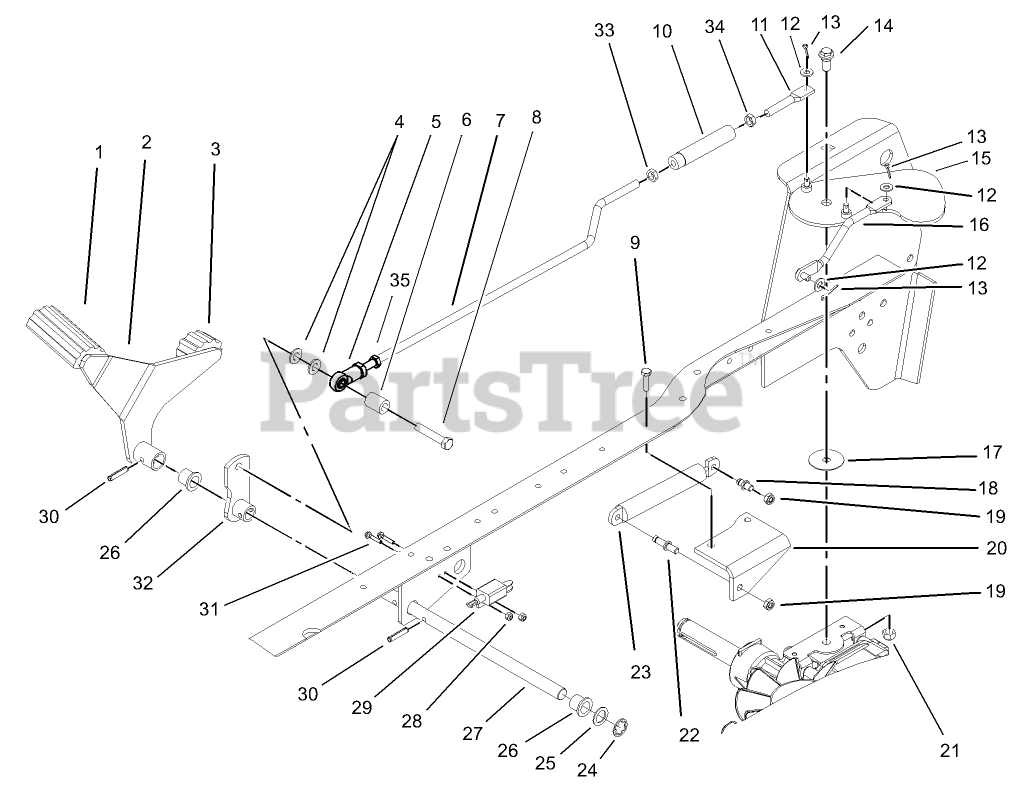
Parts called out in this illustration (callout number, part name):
2	HYDRO PEDAL ASM
3	PAD-PEDAL
4	WASHER-FLAT
5	END-ROD, FEMALE
6	TUBE-INTERLOCK
7	ROD-HYDRO
8	SCREW-HH
9	SCREW-HWHTF
10	TURNBUCKLE
11	LINK-HYDRO
12	WASHER-PLAIN
13	PIN-COTTER
14	BOLT-SHOULDER
15	CRUISE PLATE ASM
16	BELL CRANK ROD ASM
17	SPACER-CRUISE
18	ARM-CONTROL, PIN DAMPER
19	NUT-LOCK, NI
20	BRACKET-DAMPER
21	NUT-HEX
22	PIN-BRACKET, DAMPER
23	DAMPER-GAS
24	RING-RETAINING
25	WASHER-FLAT
26	BUSHING-FLANGE
27	SHAFT-PIVOT, HYDRO
28	NUT-LOCK
29	SWITCH-ADJUSTABLE
30	PIN-SPRING
31	SCREW-SHWH
32	HYDRO LINK ASM
33	NUT-HJ
34	NUT-JAM
35	NUT-JAM
